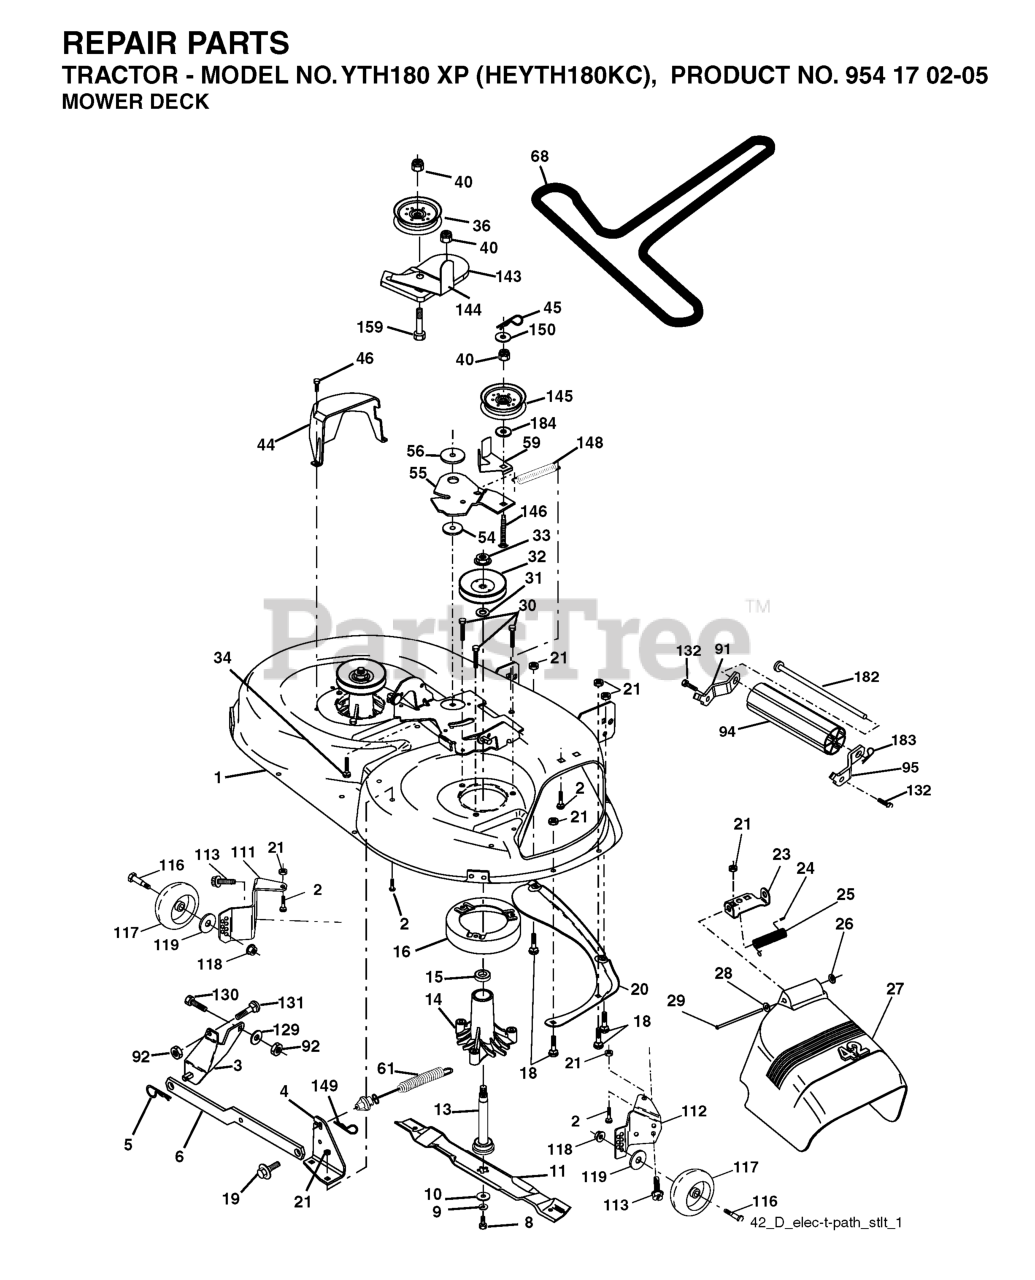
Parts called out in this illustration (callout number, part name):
1	42" DECK KIT
2	RP BOLT 5/16-18 X3/4 ZN/YEL GR
3	BRKT ASM SWAY BAR
4	BRACKET SWAY BAR 42" DECK
5	RETAINER-SPRNG RB
6	BAR SWAY DECK
8	BLADE BOLT
9	LOCKWASHER
10	WASHER.BLADE
11	42" HI-LIFT BLADE
13	SHAFT ASM VENT
14	HOUSING.MANDREL.VENTED (MACHD)
16	STRIPPER.MANDREL.ROUND.BLACK
18	BOLT
19	BOLT SHD 5/16-18
20	BAFFLE.VORTEX
21	LOCKNUT
23	BRKT, DEFL. MOWER
24	CAP-SLEEVE LT
25	SPRING TORSION
26	NUT PUSH M
27	SHIELD DEFLECTOR
28	Washer 11/32 x 5/8 x 16 Ga SD
29	ROD.HINGE
30	SCREW, WASHER HEAD
31	WASHER.SPACER.MANDREL
32	PULLEY/MANDREL
33	NUT, FLG TOPLOCK 9/16"
34	BOLT.3/8-16X1.50
36	FLAT IDLER PULLEY
40	NUT LOCK FLG 3/8-16 UNC
44	GUARD MANDREL LH BLACK
45	RETAINER M
46	SCREW.1/4-20X5/8
55	ARM IDLER 42" MOWER LT/YT
56	SPACER.RETAINER.MOWER
59	GUARD, BELT
61	SPRING EXT ELEC CLUTCH
91	BRACKET ASM NOSEROLLER LH
92	NUT
94	NOSE ROLLER
95	BRACKET ASM NOSEROLLER RH
111	BRACKET, WHEEL
112	BRACKET, WHEEL
113	BOLT.5/16HEX.WHS.HD
116	BOLT M
117	WHEEL.GAUGE.STANDARD
118	LOCKNUT
119	WASHER.5/16.FLAT.STE.STD.
129	WASHER
131	BOLT D
132	SCREW, 3/8-16X3/4
143	BRACKET, ARM IDLER
144	DNO KEEPER.BELT.42".CLUTCH.CBL
145	PULLEY
146	BOLT, CARRIAGE IDLER BLACK
148	IDLER RETURN SPRING
149	SPRING.RETAINER.YELLOW.ZINC
182	ROD ROLLER NOSE STANDARD
183	SPRING RETAINER
184	WASHER
